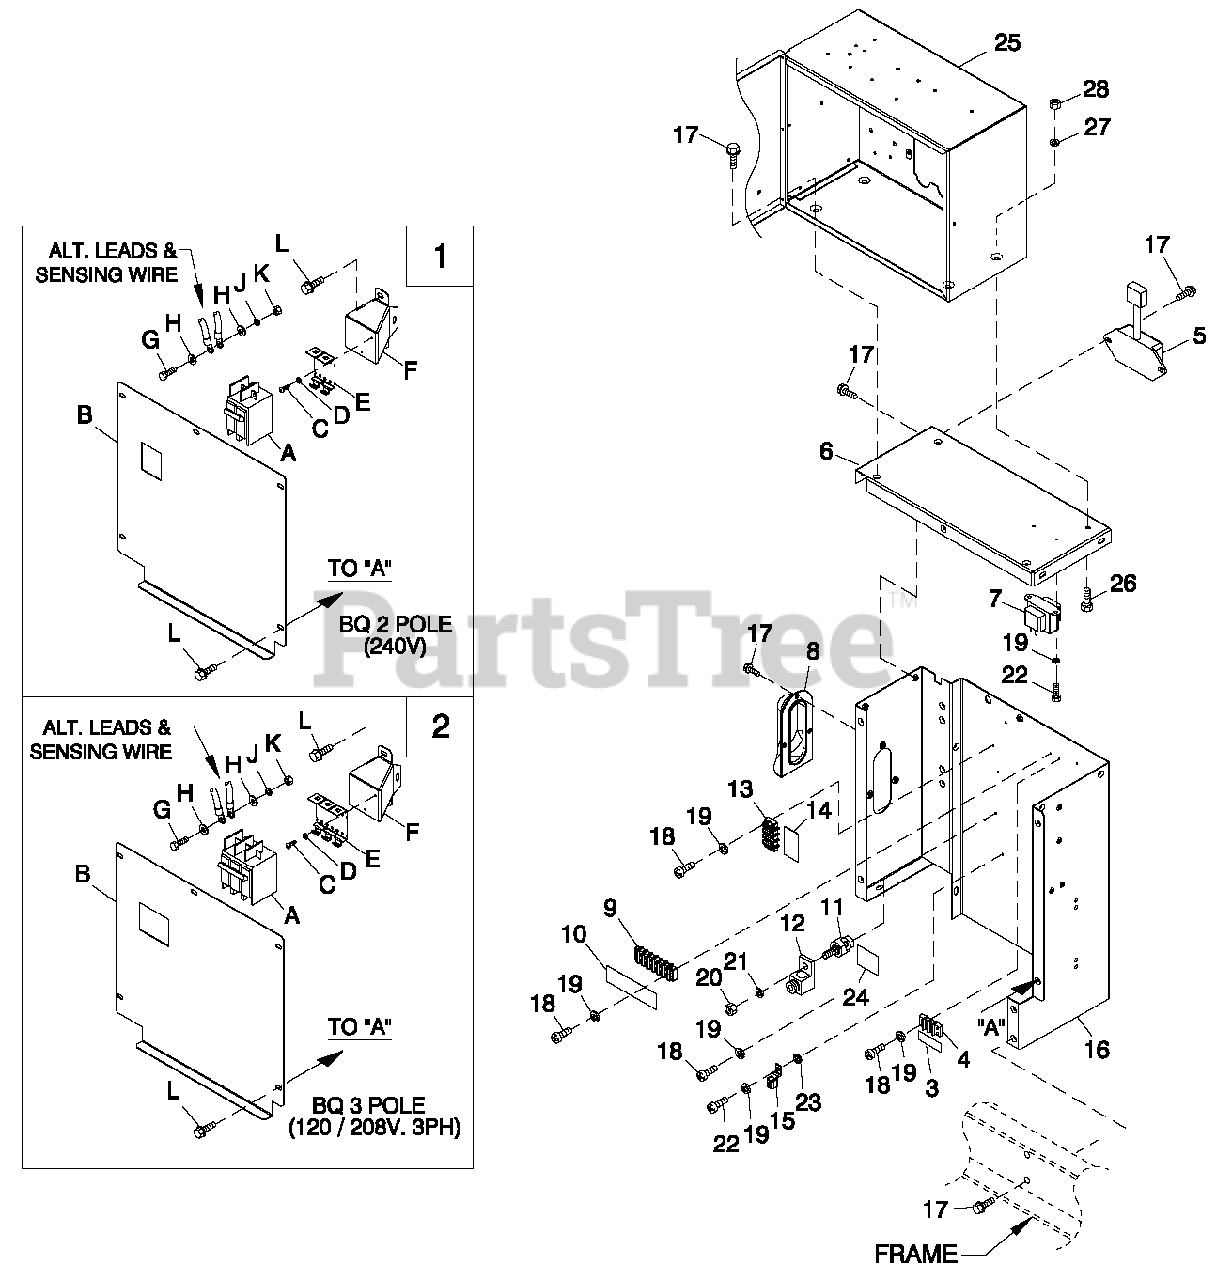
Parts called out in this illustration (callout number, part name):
3	DECAL GTS CUSTOMER CONNECTION
4	BLOCK TERM 20A 2 X 6 X 1100V
5	REGULATOR - DC ALT (1.6LONLY)
6	CONBOXTOP PANEL SUPPORT
7	XFMR208TO 16V6VA (208V. ONLY)
8	COVER BELL HOUSING CONBOX
9	BLOCK TERM 20A 6 X 6 X 1100V
10	DECAL RTS CUSTOMER CONNECTION
11	JUNCTION BLOCK 3/8-16
12	LUG SLDLSS 350-#6X13/32 AL/CU
13	BLOCK TERM 20A 6 X 3 X 1100V
14	DECAL C HARGER POWER 120VAC
15	LUG SLDLSS (6-14X 13/64CU
16	CONBOX BACK&SIDES1.6L
17	SCREW HW HTF M6-1.0X16
18	SCREW P HTTM4-0.7X16ZYC
19	WAS HER LOCK #8-M4
20	NUT HEX 3/8-16 STEEL
21	WAS HER LOCK 3/8
22	SCREW P HTTM4-0.7X8ZYC
23	WAS HER S HAKEPROOF EXT #10 STL
24	DECAL NEUTRAL
25	ASSY R-200 3600 1.6L
26	SCREW H HC M6-1.0X 16 G8.8
27	WAS HER LOCK M6-1/4
28	NUT HEXM6X1.0G8YELCH R
A	CB0090A2P 240V SBQ 2 LL
B	CB COVER 20-25K1P(BQ2)
C	SCREW P H TTM4-0.7X8ZYC
D	WAS H ERLOCK#8-M4
E	BRKT CB MTG BACK
F	CIRCUIT BREAKER SUPPORT (BQ)
G	SCREW H H C M5-0.8X20G8.8
H	WAS H ER FLAT #10 ZINC
J	WAS H ER LOCK M5
K	NUT H EX M5-0.8 G8 CLEAR ZINC
L	SCREW HW HTF M6-1.0X 16
A	CB0070A3P 240V SBQ 3 LL
B	CB COVER 20-25K3P (BQ3)
